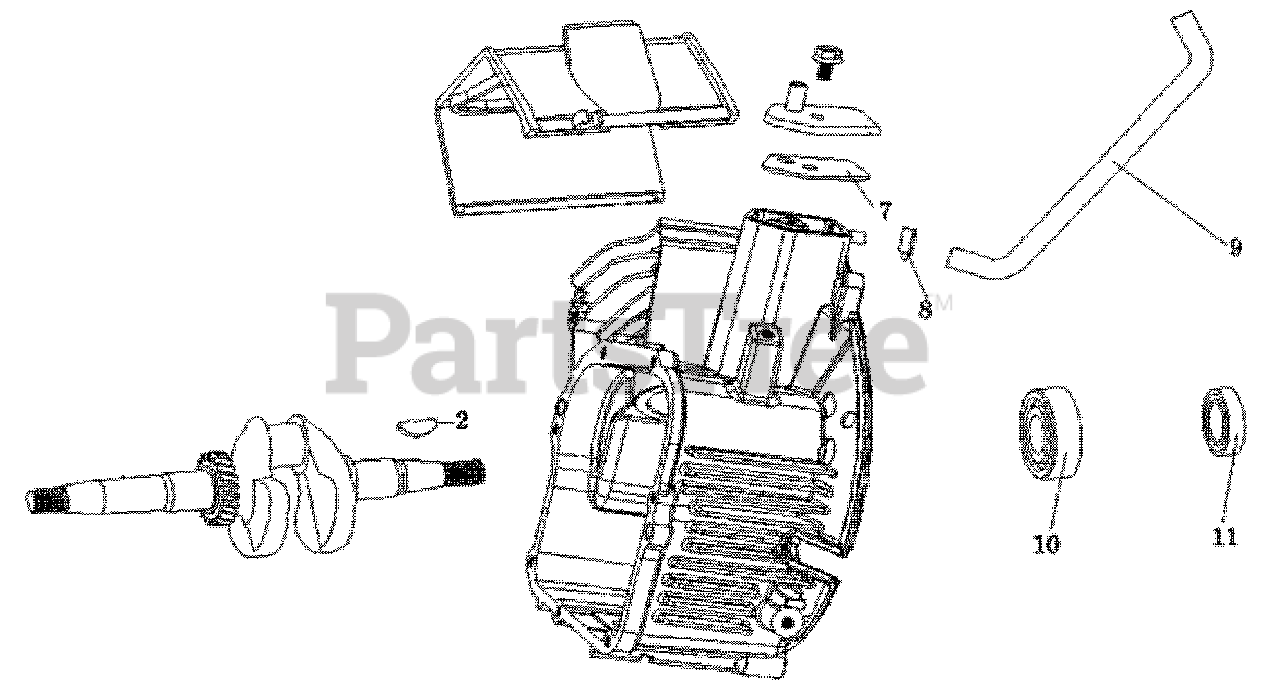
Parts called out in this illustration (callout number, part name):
2	WOODRUFF KEY
7	PACKING, BREATHER CHAMBER
8	LOOP, TUBE
9	TUBE, BREATHER
10	BALL BEARING
11	OIL SEAL
